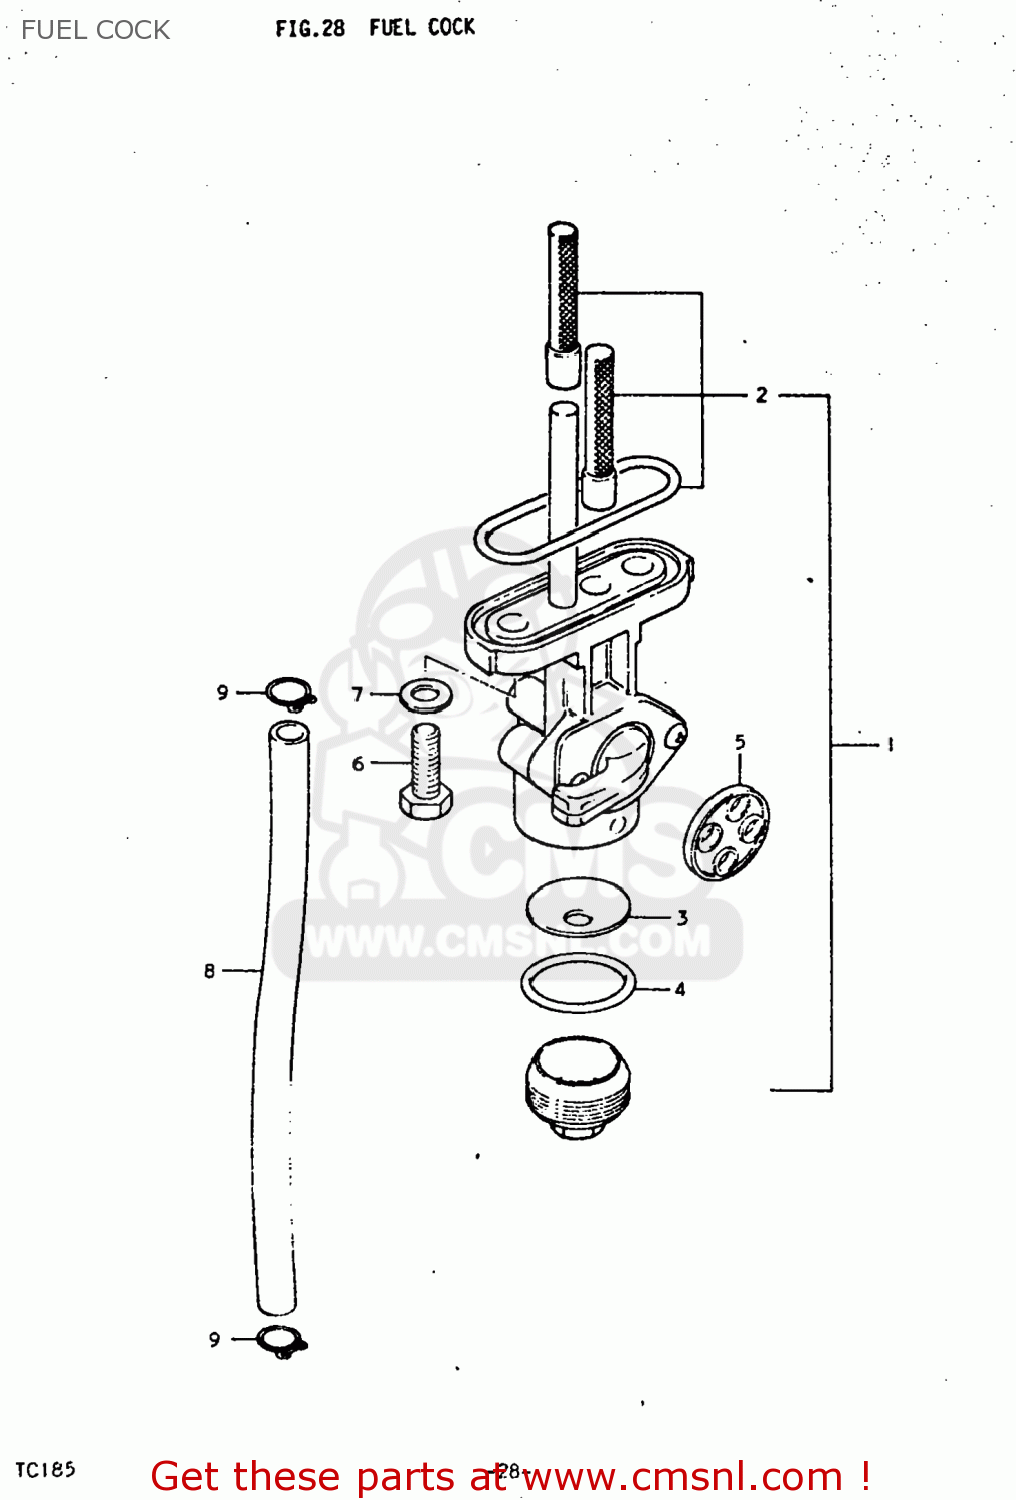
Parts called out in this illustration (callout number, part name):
1	COCK ASSEMBLY,FUEL
2	FILTER SET,FUEL COCK
3	NET,STRAINER
4	GASKET,FILTER (NAS)
5	GASKET,LEVER (NAS)
6	SCREW
7	GASKET
8	HOSE
9	CLIP
